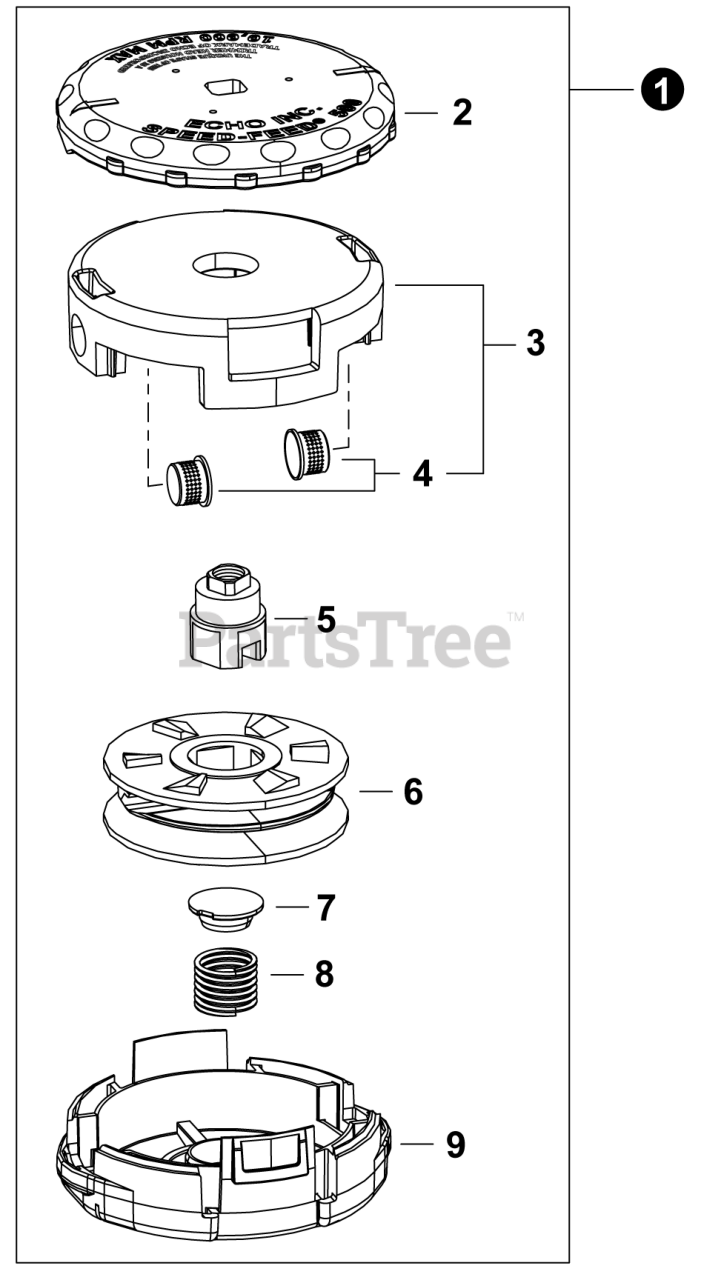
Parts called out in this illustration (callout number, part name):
1	TRIMMER HEAD, SPEED-FEED® 500
2	KNOB
3	HOUSING ASSY, SPOOL
4	EYELET
5	BUSHING 10MMx1.25 LH
6	SPOOL LH
7	CAP, SPRING
8	SPRING, GOLD
9	COVER, SPOOL
